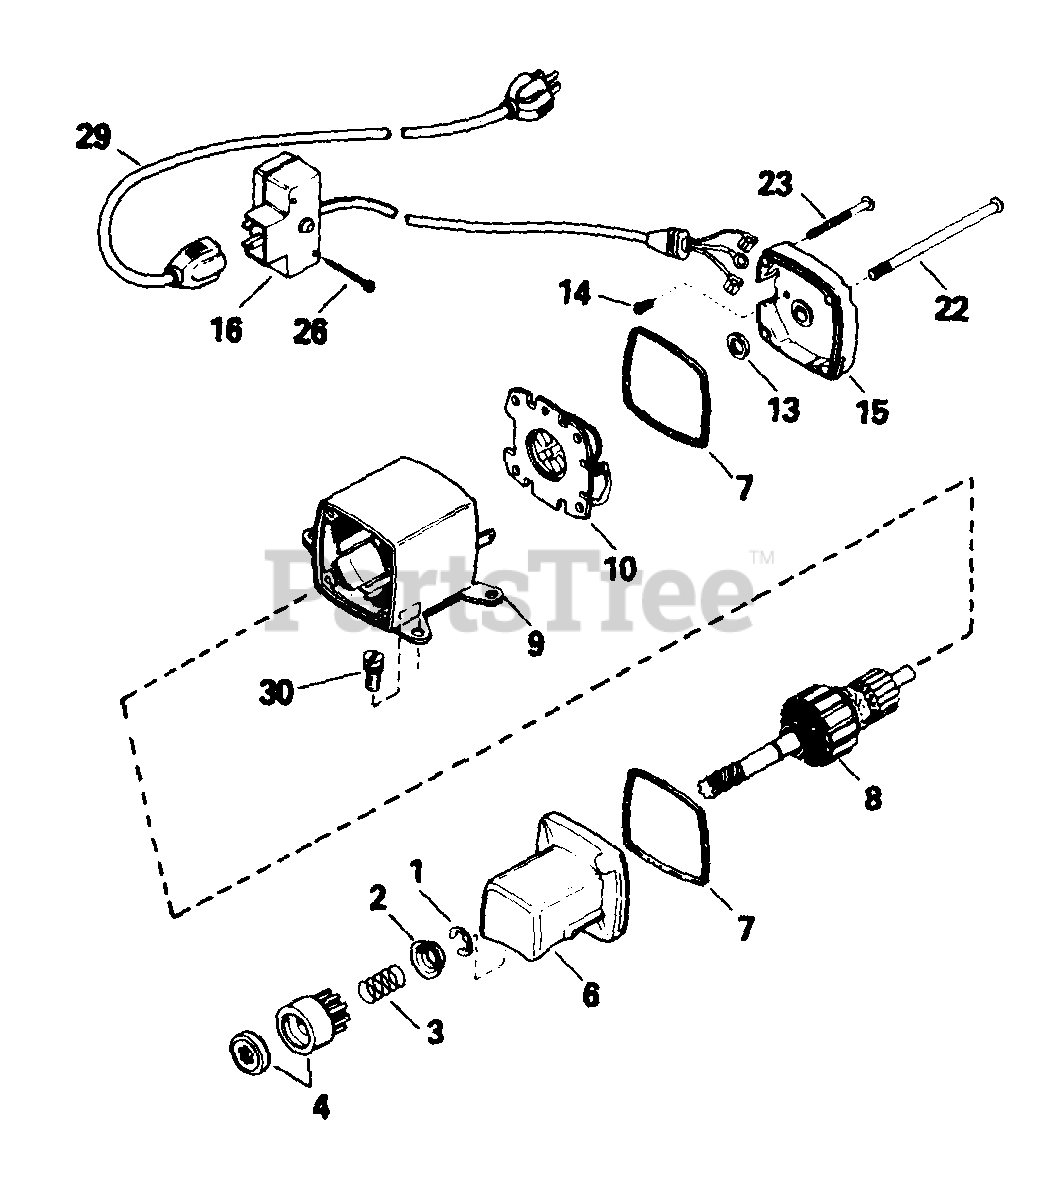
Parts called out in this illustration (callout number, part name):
1	Ring, Retainer
2	Retainer, Spring
3	Spring, Anti-Drift
4	Nut & Gear
6	Cap Ass'y,, Drive End
8	Armature
9	Housing Ass'y.
10	Card Ass'y., Brush
13	Washer, Thrust
14	Screw, Ground
15	Cap Ass'y., Commutator End
16	Box Ass'y., Switch
22	Bolt, Case
23	Screw, Grounding
26	Screw, Hex Hd. Self-Tap, 6-32 x 2-1/2
29	Cord, Extension (10'6")
30	Screw, Hex Hd. Self-Tap, 1/4-20 x 11/16
